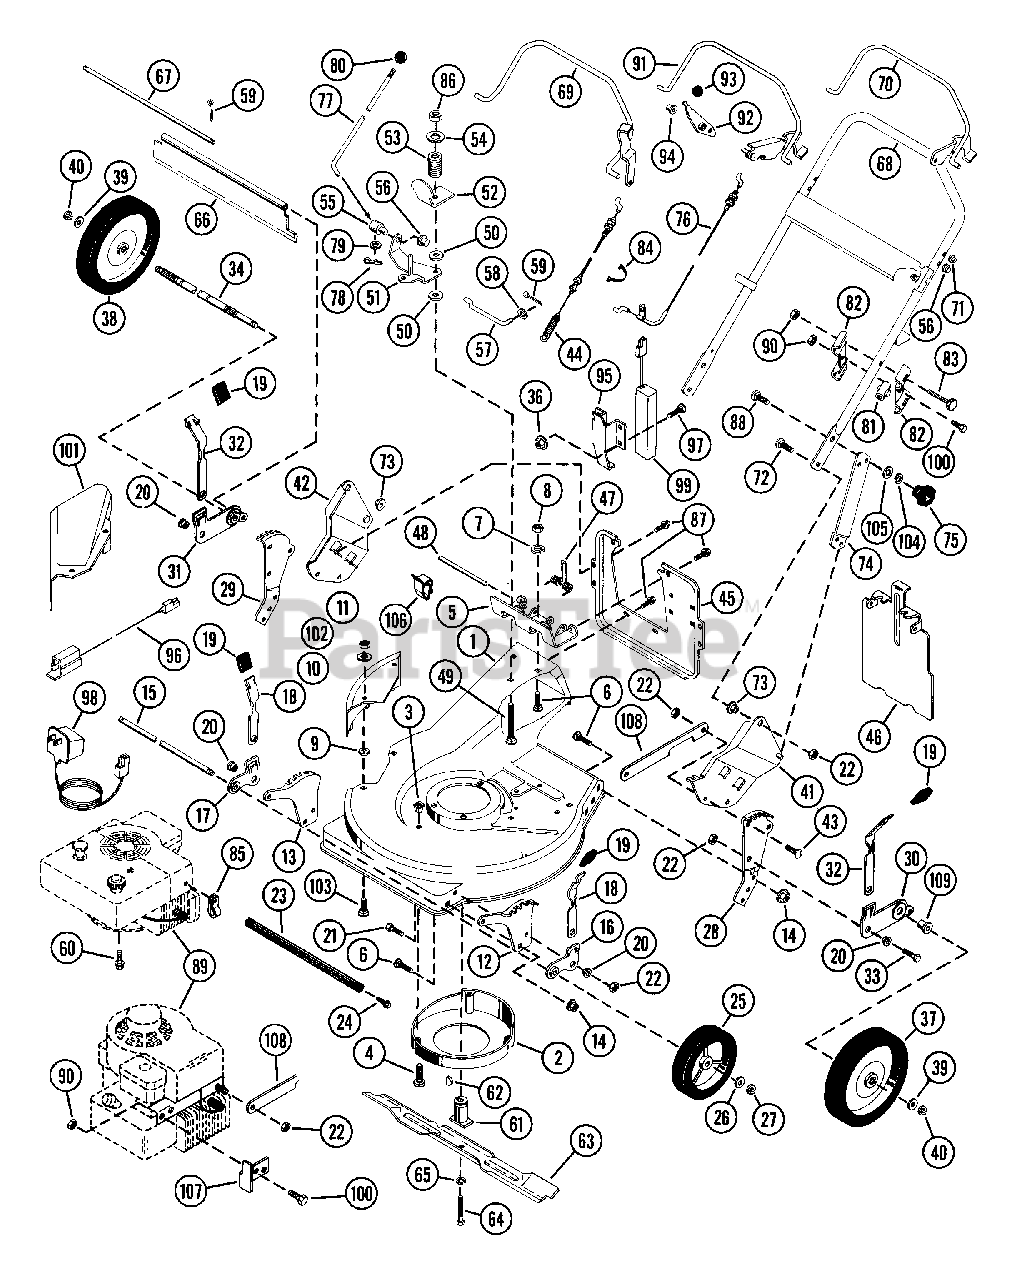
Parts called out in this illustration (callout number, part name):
1	21 INCH MOWER PAN W/DECALS
2	CENTER BAFFLE
3	PLASTIC GROMMET
4	SCR-TAP 10-16X.62 SLPH PL AB
5	HINGE PLATE
6	BLT-RDHDSQNK .312-18X.62SHTPL
7	WSHR-LK .312X.097 PL HVY
8	NUT-HEX .312-18
9	NUT-PUSH .312
10	SIDE DISCHARGE COVER
11	NUT-LK-NYL.312-18 PL
12	LEFT FRONT QUADRANT
13	RIGHT FRONT QUADRANT
14	NUT-FLG. .312-18 PL
15	FRONT AXLE
16	LEFT ADJUSTOR BRACKET ASSEMBLY
17	RIGHT ADJUSTOR BRACKET ASSEMBL
18	FRONT HEIGHT ADJUSTMENT LEVER
20	BSHG-FLG .315X.500X.354X.875
21	BLT-HEX .31-18X.75 PL GR2
22	NUT-LK .312-18 GR A PL
24	BLT-SCRHFWH .38-16X.75 PL
25	T/WHL ASSY 7X1.50
26	WSHR-FL-STL .505X.880X.072 PL
27	RG-RTNG-EXT .438X.035
28	LEFT REAR QUADRANT
29	RIGHT REAR QUADRANT
30	REAR ADJUSTMENT BRACKET LH
31	REAR BRACKET AND BEARING ASSEM
32	HEIGHT ADJUSTMENT LEVER
33	BLT-HEX .31-18X.75 PL GR2
34	REAR AXLE
35	BLT-SERHFWH .25-20X.50 PL
36	NUT-LK-FLG .250-20 PL
37	WHEEL ASSEMBLY L.H.
37	BSHG-FLG .625X.750X.750X1.125
37	BSHG-SLV .625X.750X.500
37	SEAL .625X.875X.125
37	SPACER .75 X .25 X .88
38	WHL 10 IN O.D.
39	WSHR-FL-STL .630X1.005X.062 PL
40	RG-RTNG-EXT .500X.042
41	LH HANDLEBAR MTG BRACKET WELDM
42	RH HANDLEBAR MTG BRACKET WELDM
43	BLT-RDHDSQNK .312-18X.62 PL
44	CABLE - TRACTION CLUTCH
45	CATCHER MOUNTING PLATE
46	DISCHARGE COVER
47	SG-TORS .090X.550X2.88
48	HINGE PIN
49	BLT-RDHDSQNK .38-16X2.00 SHTYW
50	FRICTION WASHER
51	BELL CRANK - SPEED CONTROL
52	PRESSURE FLANGE
53	SG-COMP .187X.56X1.62
54	WSHR-FL-STL.406X.812X.065PL
56	CAP, 3/8 ROD YWZC
57	SHIFT LINK
58	WSHR-FL-STL.281X.62X.065 PL
59	PIN-COTR .06X.50
60	SCREW - FLG WIZ LOCK HH PL
61	BLADE ADAPTER
62	KEY-WDRF .156X.625X.25 SAE 6
63	21" MOWER BLADE
64	BLT-HEX .38-24X2.00 PL GR5
65	WSHR-LK .375X.094 MED PL
66	REAR PROTECTIVE GUARD
68	HANDLEBAR W/DECAL
69	DRIVE-BAIL WELDMENT
70	START BAIL - RECOIL
71	NUT-PUSH .312 DIA. PAL
72	BLT-RDHDSQNK .31-18X.75 GR5 PL
73	BSHG, FLG .325X.499X.26X.88
74	HANDLEBAR BRACKET
75	FLUTED WING
76	CABLE - ENGINE
76	ENGINE CABLE
77	ROD - SPEED CONTROL
78	PIN-HAIR INT .08X.18X1.18
79	WSHR-FL-STL.344X.688X.065PL
81	PULL CORD RETAINER
82	BRACKET - ROPE GUIDE
83	BLT-HEX .25-20X1.50 PL GR5
84	CABLE RETAINER
85	CLIP
86	NUT-LK-CTR .375-16 GR A PL
87	SCR-TAP 10-24X.375 HWH PL TR
88	BLT-RDHDSQNK .31-18X1.25 SHTPL
89	ENGINE
90	NUT-LK-CTR .250-20 PL
91	START BAIL WELDMENT - ELECTRIC
92	START LEVER WELDMENT
93	KNOB, CONTROL-THROTTLE
94	PUSH NUT, .25
95	BATTERY BOX
96	POWER CORD
97	BLT-RDHDSQNK .25-20X.50 SHT PL
98	BATTERY CHARGER
99	BATTERY
100	BLT-HEX .25-20X.50 PL GR2
101	DISCHARGE CHUTE
102	WSHR-FL-STL .38X.875X.083 PL
103	BLT-RDHDSQNK .31-18X.75 SHT PL
104	WSHR-LK .500X.151 HVY PL
105	WSHR-FL-STL .323X.625X.062 PL
106	CLIP-HARNESS TINNERMAN
107	LEVER GUARD
108	ANTIVIBRATION STRAP
109	BRG-BALL .750X1.50X.44
